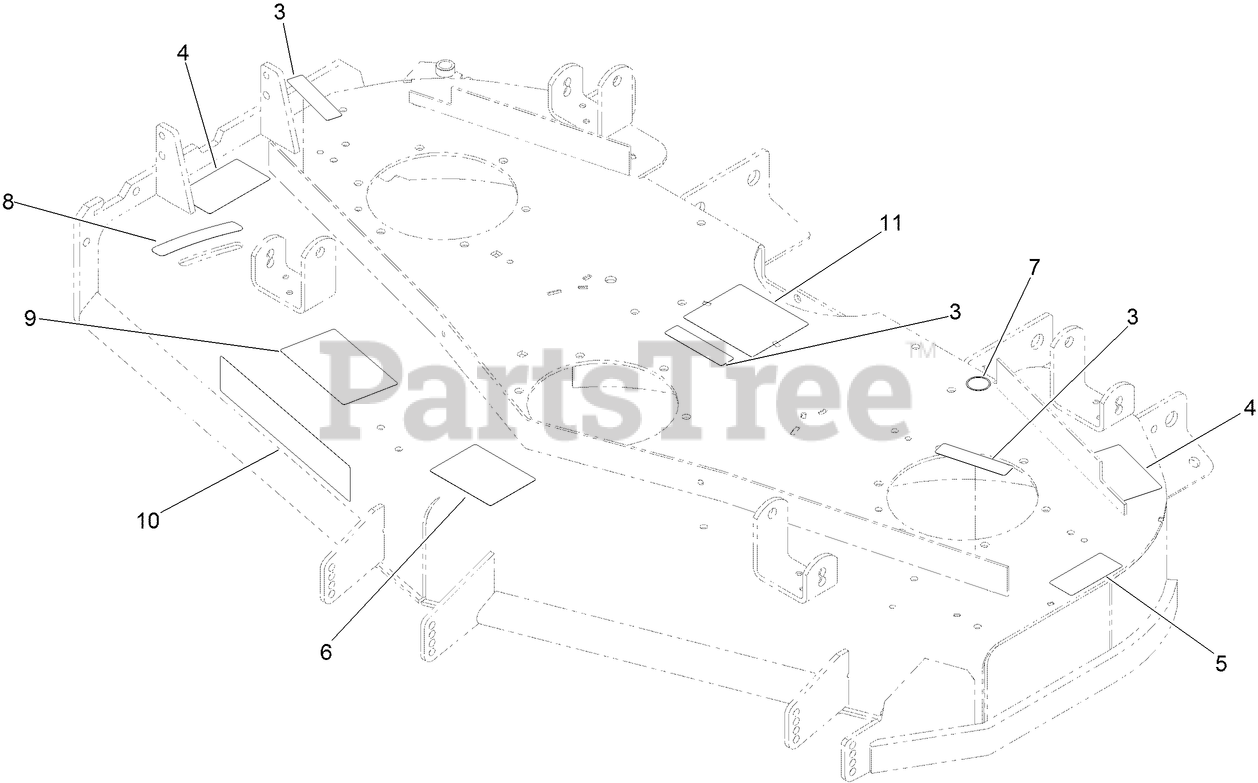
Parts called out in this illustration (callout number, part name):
3	DECAL-WARNING
4	DECAL-DANGER
5	DECAL-BOLT TORQUE
6	DECAL-SCALP, ANTI
7	DECAL-GREASE
8	DECAL-SETTING, BAFFLE
9	DECAL-ADJUSTMENT, BAFFLE
11	DECAL-ROUTING, BELT
